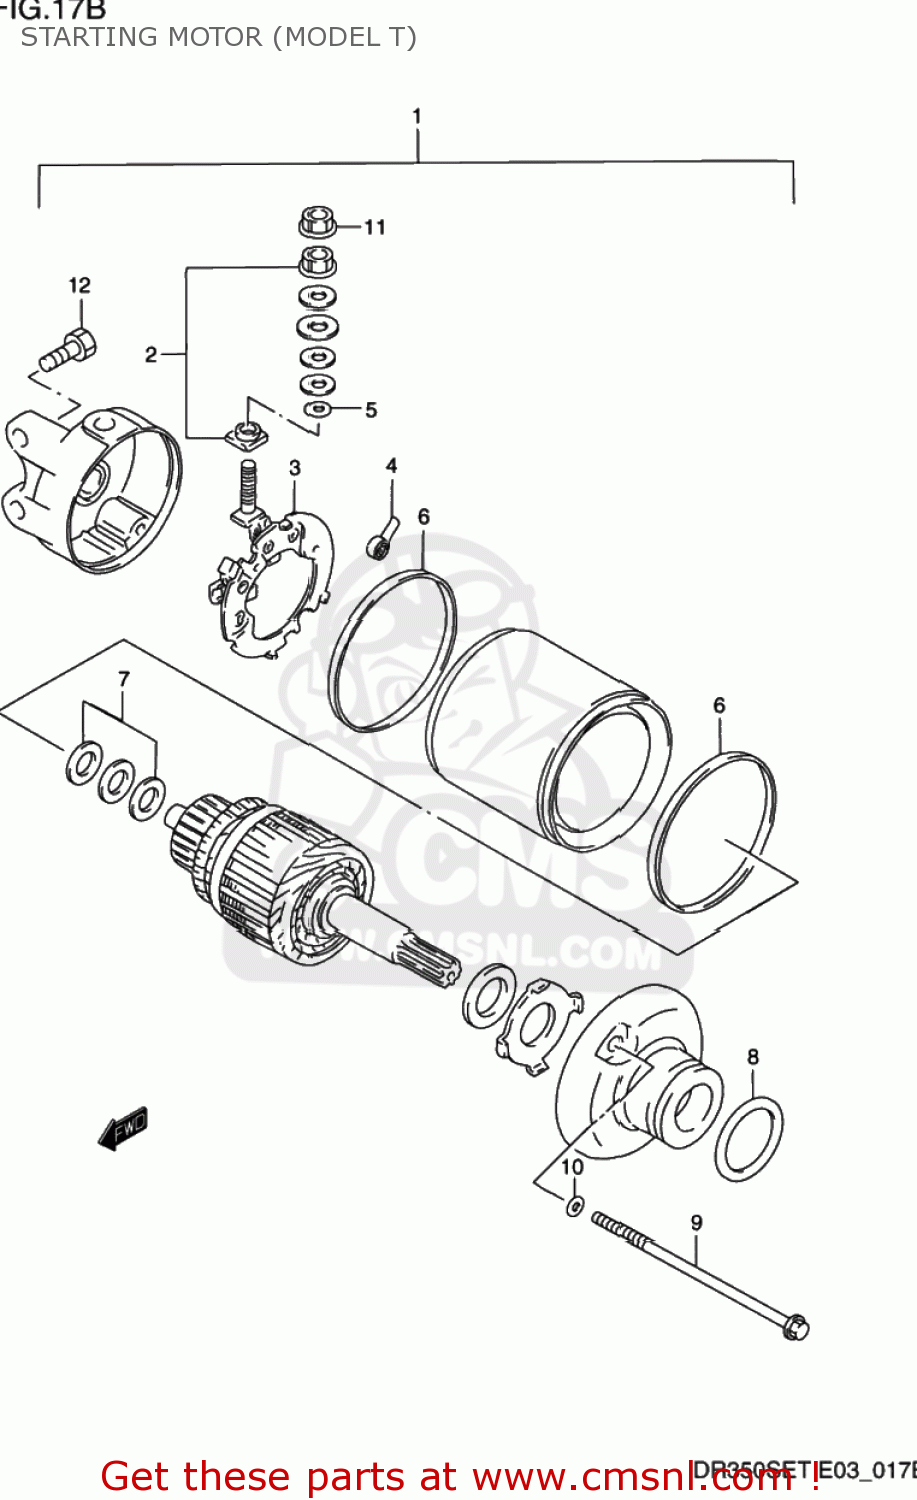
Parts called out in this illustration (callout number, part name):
1	MOTOR ASSY,STARTING
2	BRUSH TERMINAL SET
3	BRUSH HOLDER SET
4	SPRING,BRUSH
5	O RING
6	O RING
7	SHIM SET,STARTING MOTOR
8	O RING
9	SET,BOLT ASSY
10	O RING(D:3,ID:24.5)
11	NUT
12	BOLT,CRKCASE,R
